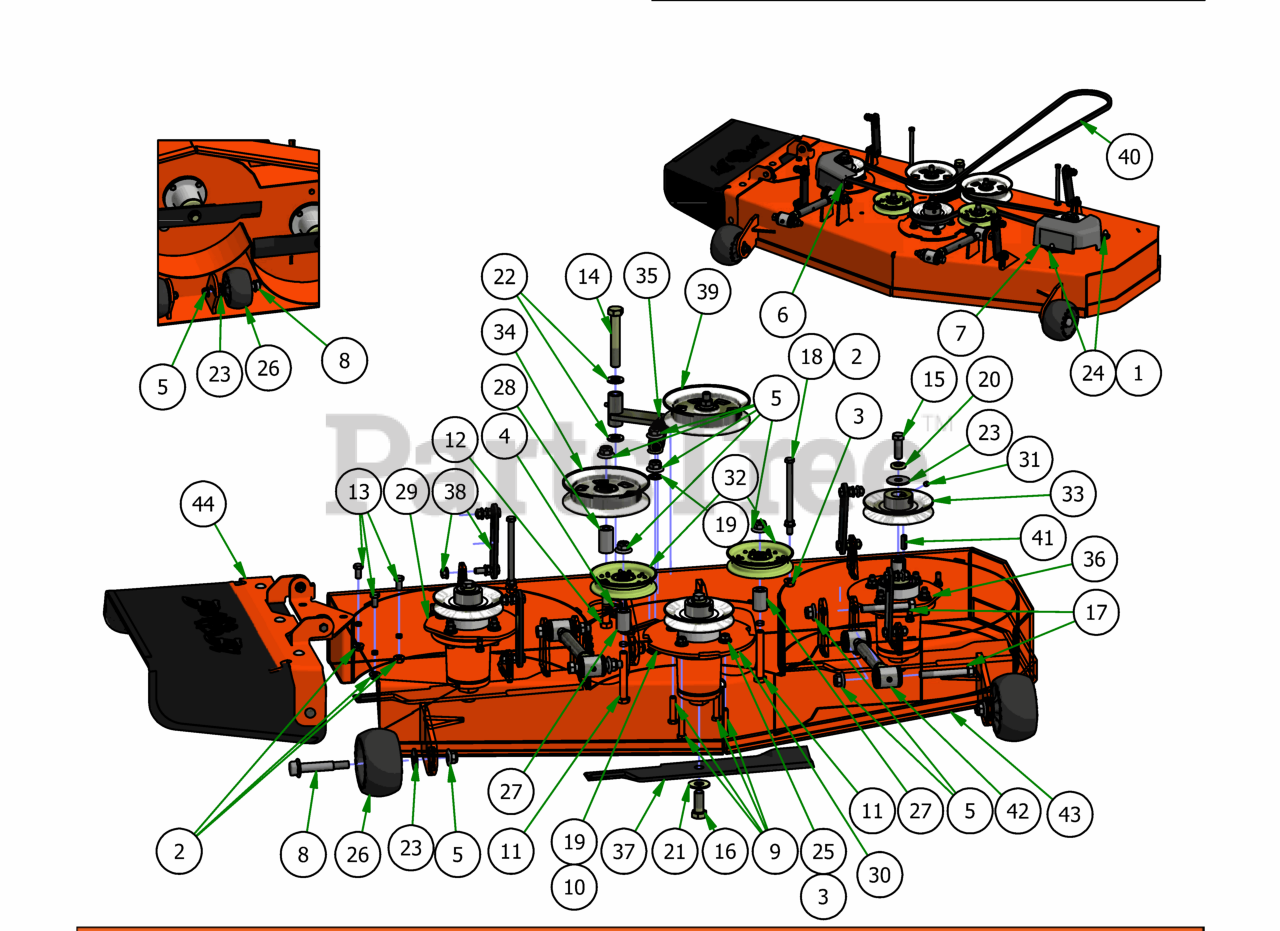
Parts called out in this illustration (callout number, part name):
1	Acorn nut-pulley Cover
2	3/8" Flange Nut
3	3/8-16 NYLON INSERT FLANGE LOCKNUT (GR.F) ZINC
4	5/8-11 Nylon Insert Jam Half Nut
5	1/2-13 NYLON INSERT FLANGE LOCKNUT ZINC
6	pulley cover chute side
7	pulley cover non-chute side
8	Deck Wheel Bolt
9	3/8-16 X 1-3/4 HEX C/S (GR.5) ZC
10	1/2 x 2" Carriage Bolt
11	1/2 x 3 1/2 Flange Bolt Grade 8
12	1/2" x 4" Bolt (Grade 8)
13	3/8" x 3/4" Hex Bolt
14	5/8" x 4" Hex Bolt
15	1/2"-20 x 1 1/2 - Grade 5 Fine Thread Bolt
16	5/8 x 1 1/2 Grade 8 Hex Bolt (Fine)
17	1/2-13 x 3 1/2 GR 5 Hex Bolt
18	3/8-16 X 5-1/2 HEX CAP SCREW (GR.5) ZINC
19	.517 Square Hole Round Washer
20	1/2" Lock Washer Zinc
21	5/8'' Flat Washer
22	.630 ID Plastic Washer
23	1/2" Belleville Washer
24	.360 ID Plastic Washer-Black
25	5/16 USS FLAT WASHER (7/8 OD) ZINC
26	Deck Wheel
27	.502 ID X .750 OD X 1.500 Long Spacer
28	1 3/4" Pulley Spacer
29	42&4 8 Deck Spindle Support Plate
30	Deck Spindle Support Plate
31	5/16 Set Screw
32	4 3/4 Idler Pulley - ABFI-76
33	5" Spindle Deck Pulley
34	5-3/4 Idler Pulley
35	Deck Idler Spring
36	Spindle Assembly
37	16 1/4" Bad Boy Blade
38	Deck Hanger Assembly
39	2017 54"/48" Deck Idler Assembly
40	B147 Deck Belt
41	1/4" x 1" Key
42	2018 Maverick Turnbuckle (Top Link)
43	2017 48" ZT Deck
44	ZT Chute Assembly
